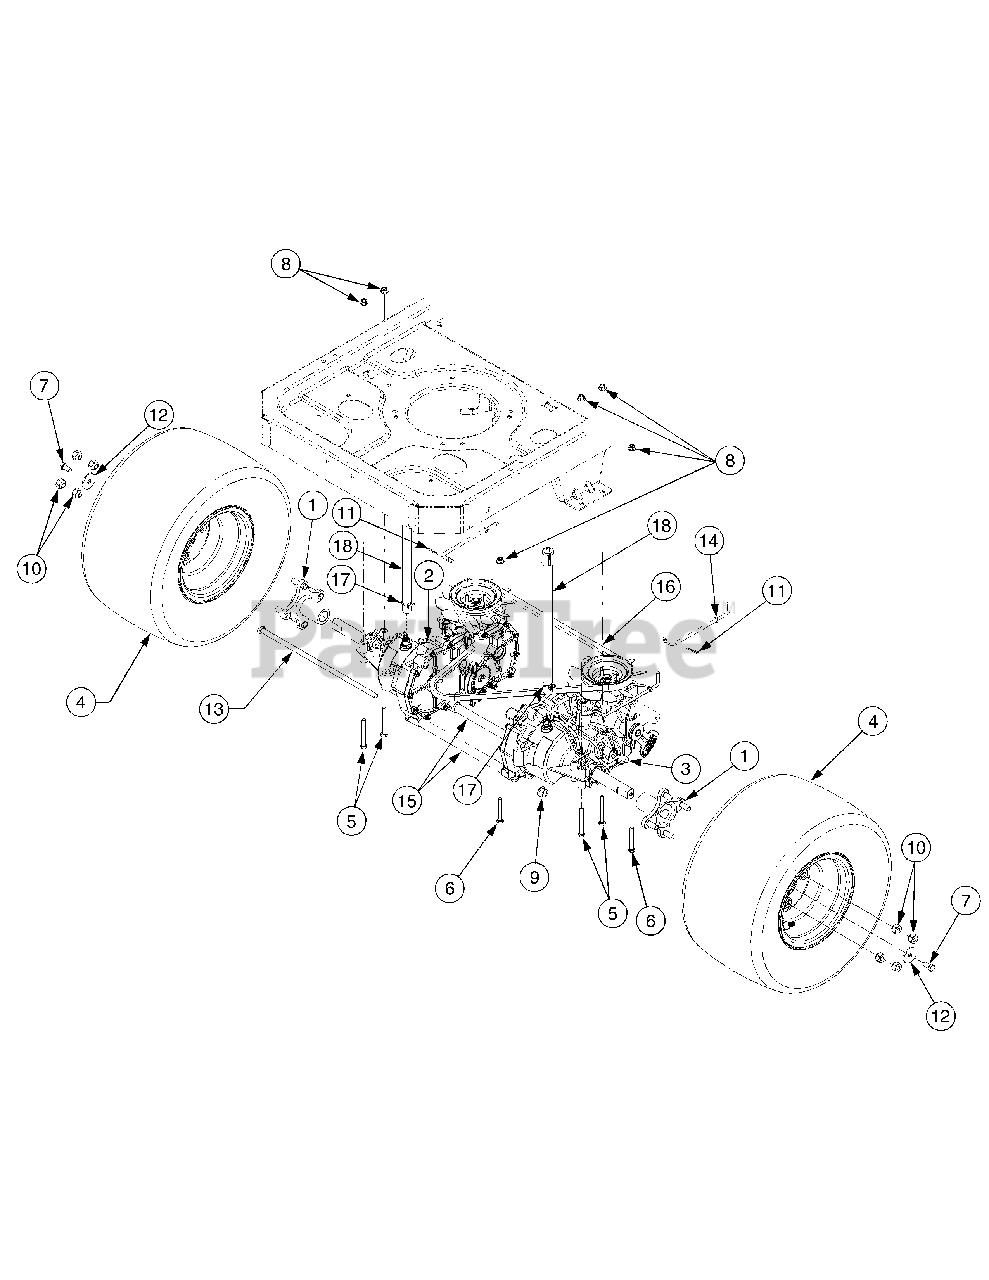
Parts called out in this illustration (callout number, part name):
2	Transmission Assembly
3	Transmission Assembly
4	ZT4200 Wheel Ass’y, 18 x 6.5 x 8
4	ZT5000 Wheel Ass’y, 18 x 9.5 x 8
5	Screw, Hex Cap, 5/16-18 x 2.75 GR5
6	Screw, Hex Cap, 5/16-18 x 2.25 GR5
7	Screw, Hex Cap Lock, 3/8-16 x .75 GR5
8	Nut, Hx Flnge Insert Lck, 5/16-18 GrF
9	Nut, Hex Flange Lock, 7/16-20 GrB .
10	Nut, Lug, 7/16-14
11	Pin, Cotter, 3/32 x .75
12	Washer, Flat, .39 x 1.5 .134
13	Rod, .405 x 14.0
15	Tube, .45 x .69 x 10.2
16	V-Belt, Type A Sec x 57.7
18	Hose, Breather
